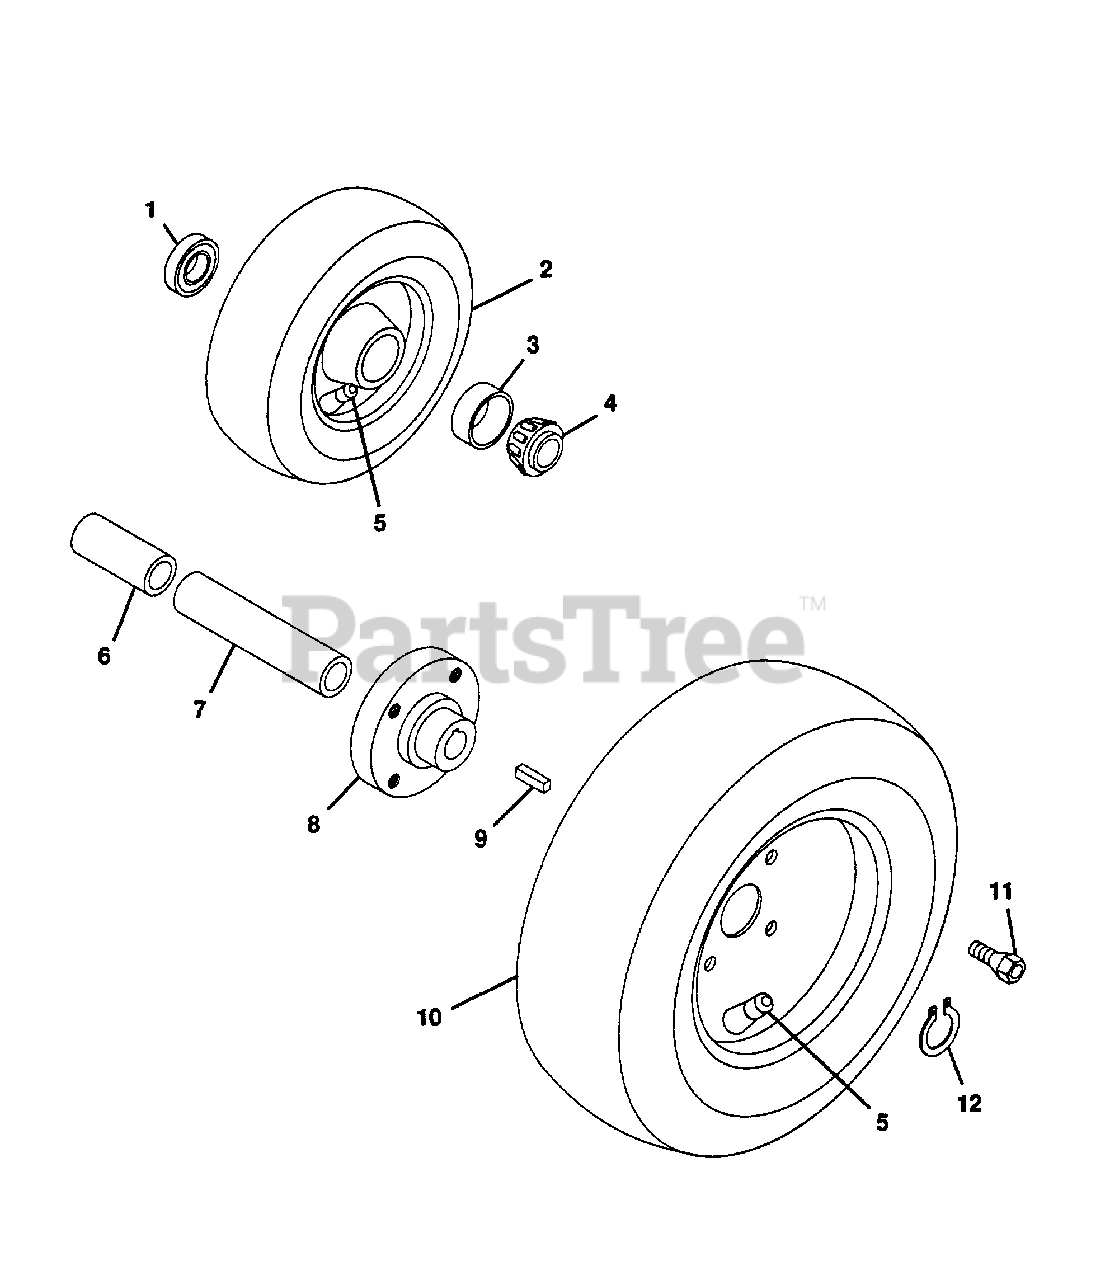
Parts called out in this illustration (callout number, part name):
1	SEAL, WHEEL
2	ASSEMBLY, WHEEL REAR
3	BEARING, CUP
4	BEARING, CONE
5	ASSEMBLY, VALVE STEM
6	BUSH., ST. 1.01X1.44X2.74 STL.
7	BUSH., ST. 1.01X1.44X2.12 STL.
8	HUB
9	KEY, SQUARE .250X1.250
10	ASSEMBLY, WHEEL
11	STUD, WHEEL
12	RING, RETAINING
